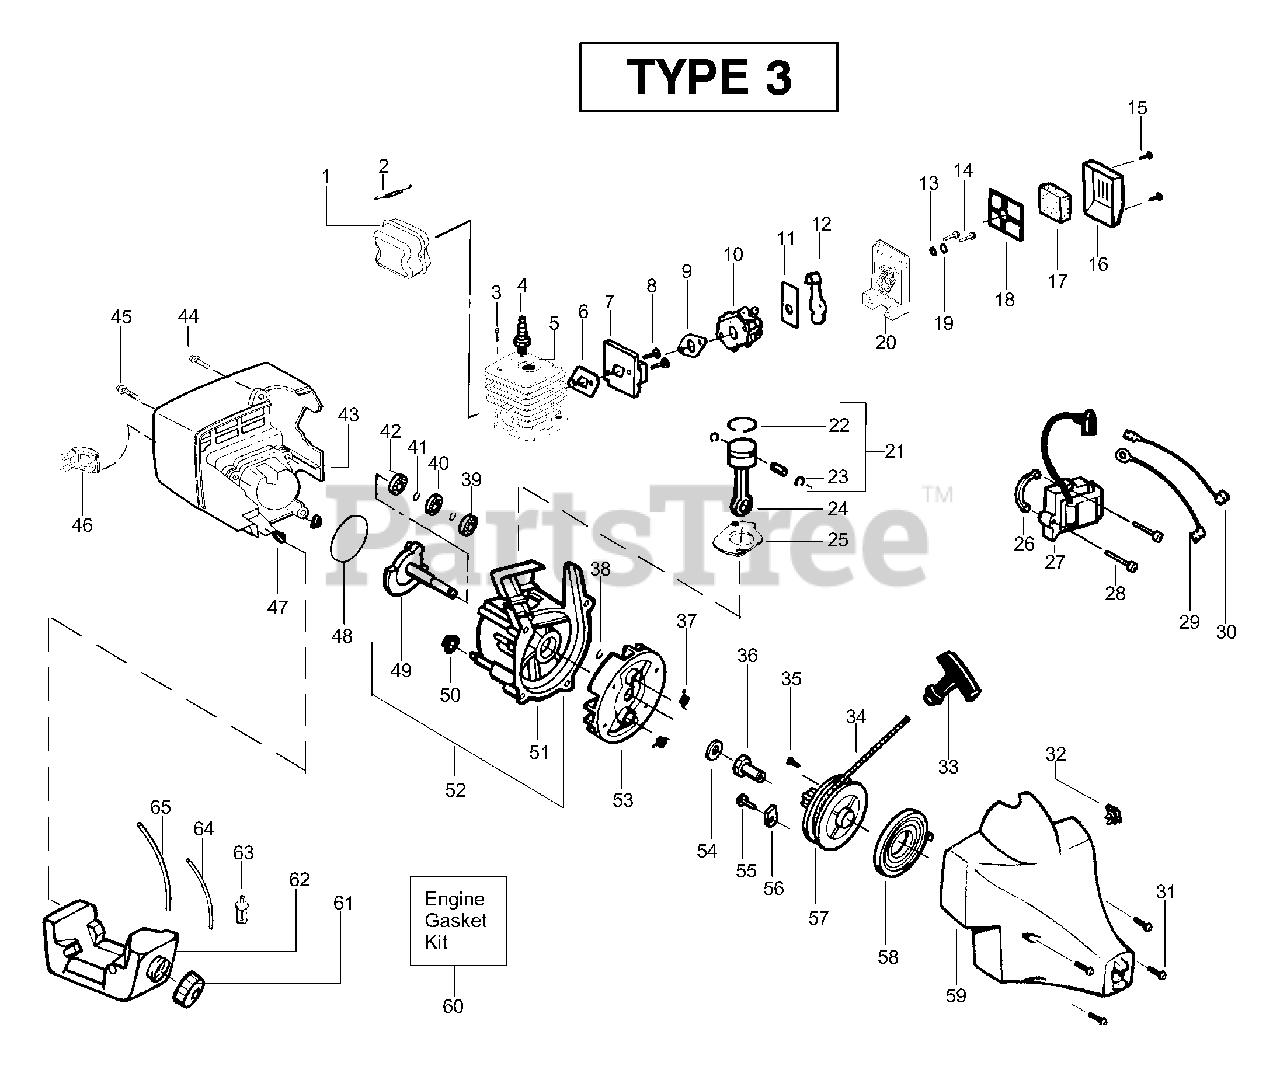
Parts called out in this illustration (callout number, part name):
1	Kit - Muffler
2	Muffler Spring
3	Screw-Cylinder
4	Spark Plug (RCJ 6Y)
5	Kit - Cylinder
6	Gasket-Cyl/Carb.(kit)
7	Adaptor-carb.
9	Gasket-Carb.(kit)
10	Kit - Carburetor Ass'y
11	Plate-Choke Mounting
12	Lever-Choke
16	Cover-Air Box
17	Foam-Air Filter
18	Plate-Air Filter Support
19	Spacer-Choke
21	Kit - Piston
22	Piston Ring
23	Retainer-Piston Pin
24	Assy-Connecting Rod
25	Gasket-Cylinder(kit)
26	Spacer-Module
27	Ignition Module
29	Assy-Ground Wire
30	Assy-Leadwire
31	Screw
32	Kit-Momentary Switch
33	Handle-Starter
34	Kit - Rope
36	Coupling-Drive
37	Spring-Starter Dog
38	Retain. Ring-C'shaft
39	Bearing-Outer
40	Seal-C'case
41	Retainer Ring-C'case
42	Bearing-Inner
45	Screw
46	Guard-Muffler
47	Isolator-Shroud
48	O-Ring-C'case(kit)
49	Assy-Crankshaft
50	Isolator-Crankcase
51	Assy-Crankcase
52	Assy-C'case & C'shaft
53	Assy-Flywheel
54	Washer-Flat
56	Retainer-Can
57	Kit-Starter Pulley
58	Spring-Starter
59	Assy-Fan Housing
60	Kit-Engine Gasket
61	Assy-Fuel Cap
62	Assy-Fuel Tank
63	Assy-Fuel Pickup
64	Kit-Fuel Line
65	Kit-Fuel Line
